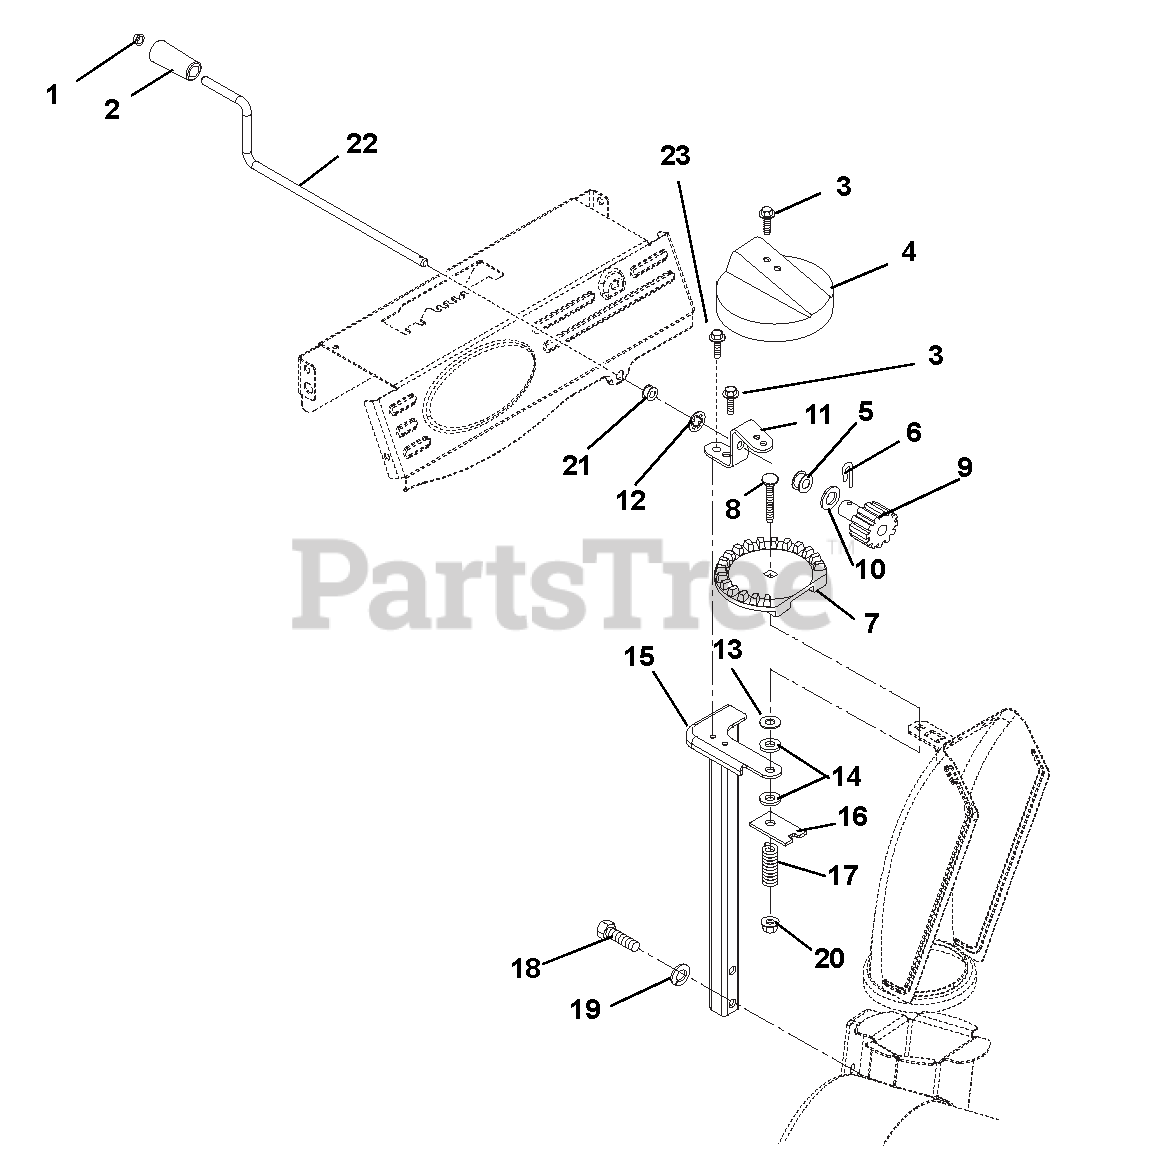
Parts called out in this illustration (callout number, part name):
1	CAP, 3/8 ROD YWZC
2	KNOB, CHUTE CRANK
3	SCR-TAP .25-20X.50 HWH TR YWZ
4	GEAR COVER
5	BUSHING, POLYLINER-.63 SNAPIN
6	PIN, SPRING CLIP
7	CHUTE GEAR
8	@BLT-RDHDSQNK .38-16X2.50 G5YZ
9	PINION GEAR W/BRACKET
10	WSHR-THRST .625 X 1.0 X .03
11	BRACKET, PINION GEAR
12	PUSHNUT .625
13	WSHR-FL-STL .380X1.50X.062 YWZ
14	FRICTION WASHER
15	CHUTE PEDESTAL, TALL COMPACT
16	PLATE, FRICTION
17	SG-COMP .187X.56X1.62
18	@BLT-HEX .38-16X1.75 GR5 YWZC
19	@WSHR-LK .38X.094 REG YWZC
20	@NUT-LK-TOP-FLG .38-16 YWZC
21	BUSHING, POLYLINER-.38 SNAPIN
22	CHUTE CRANK,COMPACT 920,XXX HI
23	SCR-TAP .25-20X.50 HWH TR YWZ
